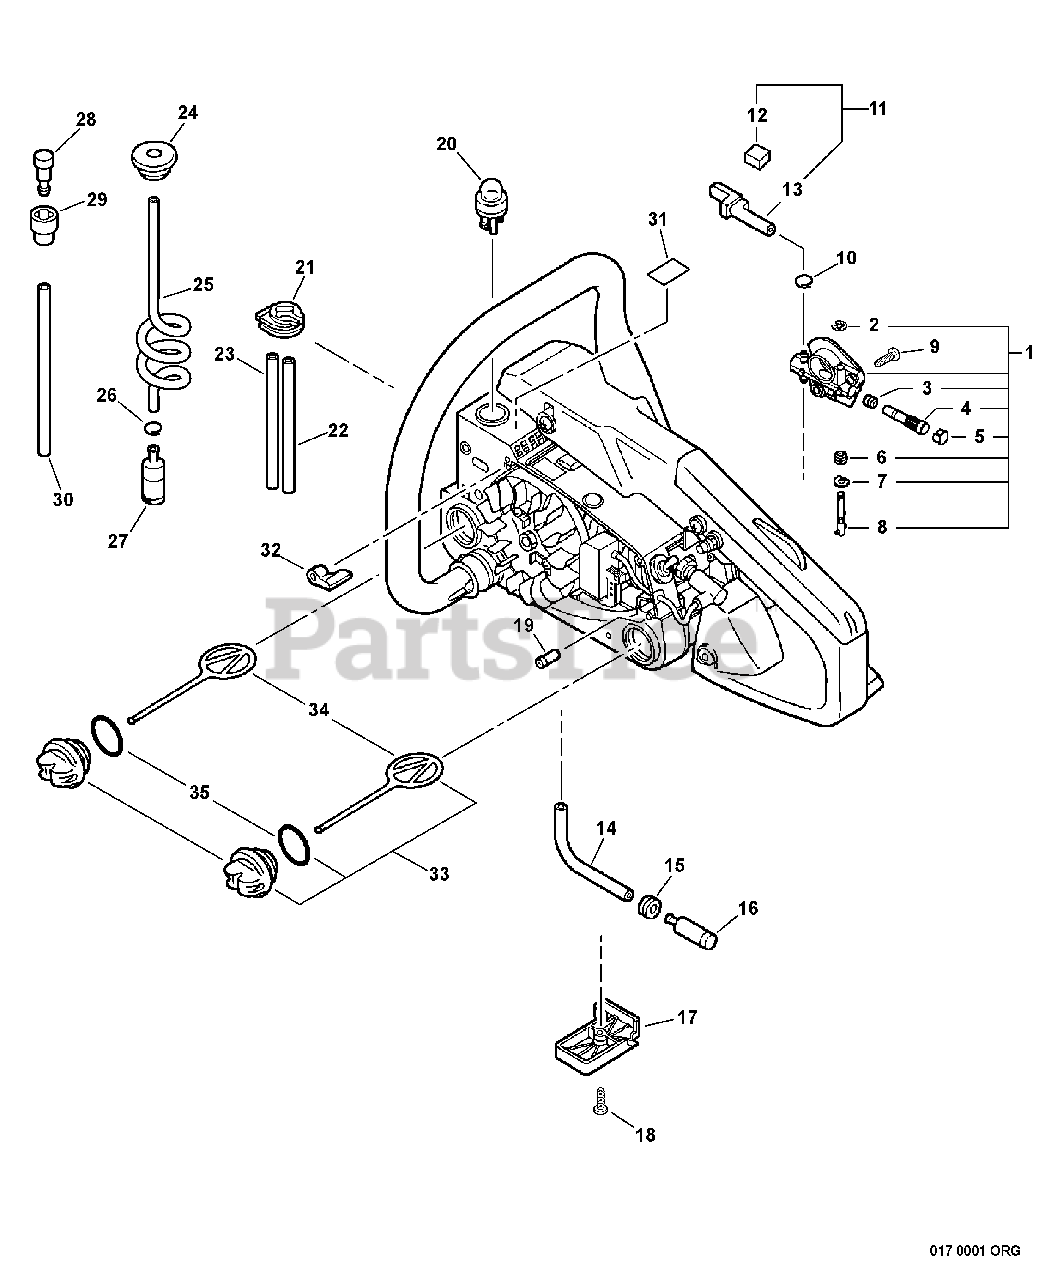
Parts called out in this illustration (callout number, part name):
1	AUTO-OILER ASSY
2	RING, RETAINING
4	PLUNGER
5	CAP, OIL PUMP
8	NEEDLE, ADJUST
9	SCREW - 5X12
10	CLIP - 6.5
11	OIL PIPE KIT
12	PAD, FOAM
13	PIPE - OIL
14	PIPE - 3X6X115 -- BLACK
15	GROMMET
16	FILTER, OIL
17	COVER, BOTTOM - ORANGE
18	SCREW - 4X16
19	VENT, TANK
20	PUMP, PURGE
22	PIPE - 3X5X70 -- BLACK
23	PIPE - 2X4X42 -- CLEAR
24	GROMMET
25	PIPE, FUEL - SPIRAL
26	CLIP - 6.5
27	FILTER, FUEL
28	VENT, FUEL TANK
29	HOLDER, VENT
30	PIPE - 3X5X150 -- BLACK
31	LABEL - PURGE PUMP
33	CAP ASSY - BLACK
34	CONNECTOR, CAP
35	O-RING - 25
